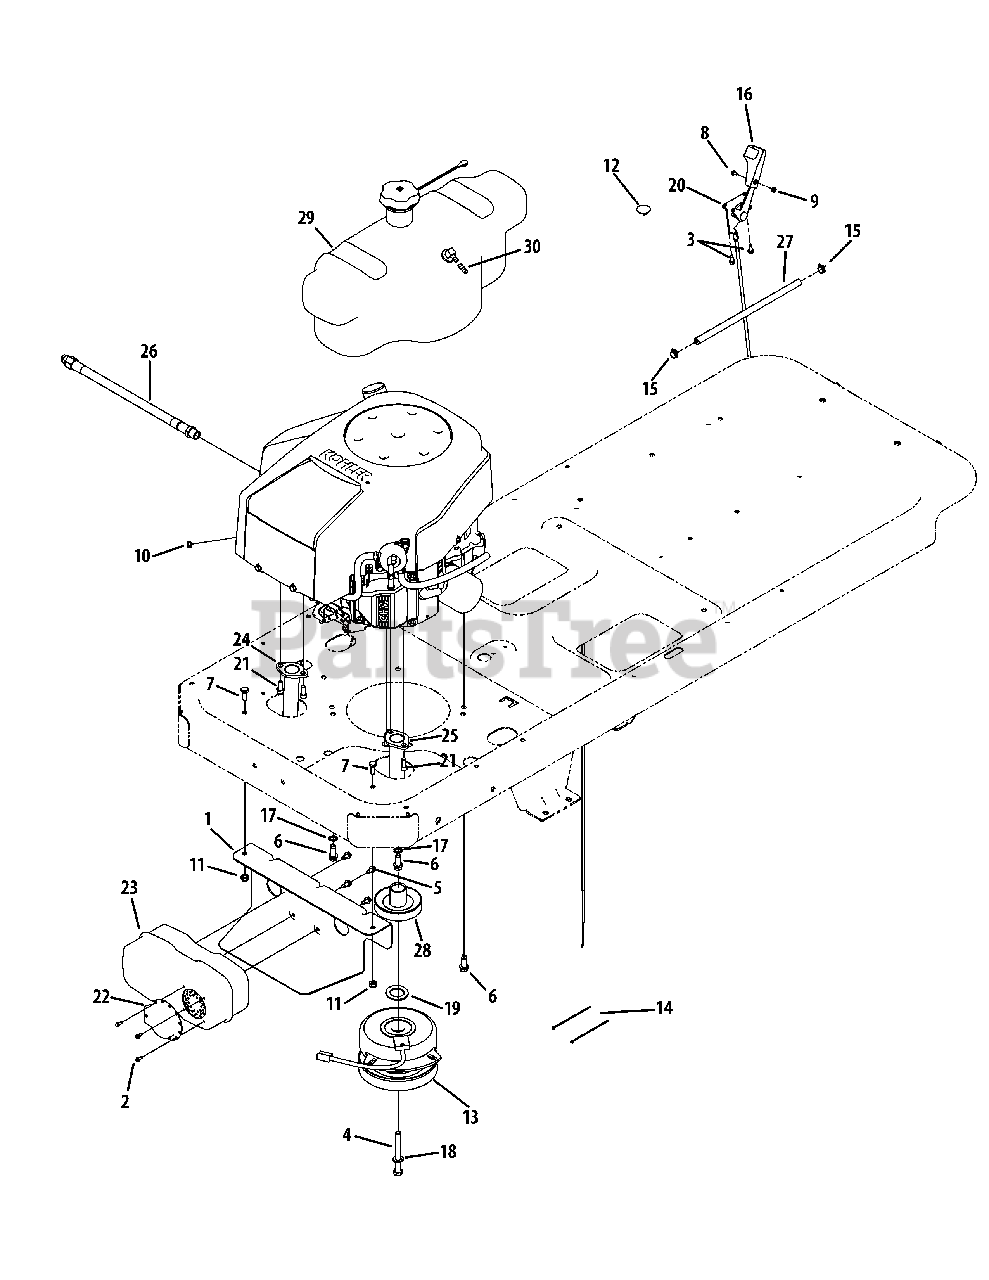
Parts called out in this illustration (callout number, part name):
1	Muffler Mount Bracket
2	Hex Washer Screw, #8-18 x .500
3	Screw, 1/4-14 x .625
4	Hex Lock Screw, 7/16-20 x 3.50
5	Hex Washer Screw, 1/4-20 x .500
6	Hex Washer Screw, 3/8-16 x 1.000
7	Hex Washer Screw, 5/16-18 x .75
8	Machine Screw, #8-32 x .375
9	Hex Nut, #8-32
10	Sems Nut, 1/4-20
11	Flange Lock Nut, 5/16-18
12	Choke Plug
13	Electric PTO Clutch
14	Cable Tie
15	Hose Clamp
16	Throttle Control Knob
17	Lock Washer, 3/8
18	Lock Washer, 7/16
19	Flat Washer, 1.03 x 1.620 x .095
20	Throttle/Choke Control Cable
21	Screw, 5/16-18 x .750
22	Muffler Deflector
23	Dual Inlet Muffler
24	Exhaust Pipe, LH
25	Exhaust Pipe, RH
26	Oil Drain Hose
27	Fuel Hose
28	Engine Pulley
29	Fuel Tank Assembly
29	Fuel Tank Bushing
29	Rubber Grommet
29	Fuel Pick-Up Fitting
29	Fuel Cap
29	Rollover Valve
30	Hose Vent, 3/16 EPA
